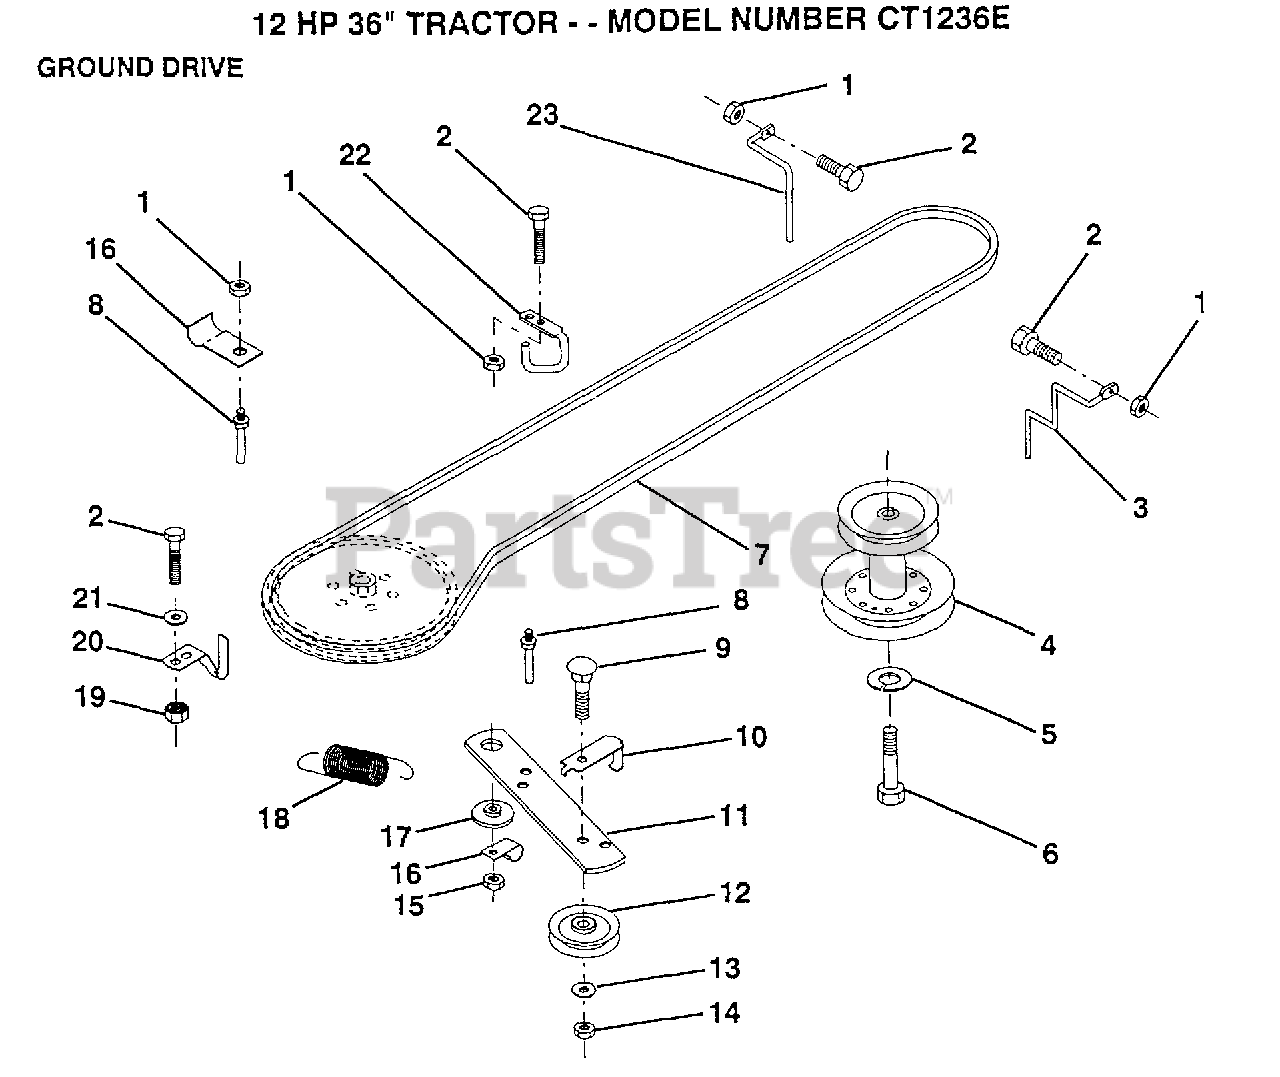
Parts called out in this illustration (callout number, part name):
2	BOLT
5	LOCKWASHER
6	HEX BOLT
7	V BELT
8	"KEEPER,DRIVE BELT"
9	BOLT
10	"KEEP,IDLER DR BEL"
13	WASHER
14	LOCKNUT
16	"CLIP,INSULATOR"
17	SPACER RETAINER
20	"KEEPER,DR BELT "
21	WASHER
22	"KEEPER,FRA DR BEL"
